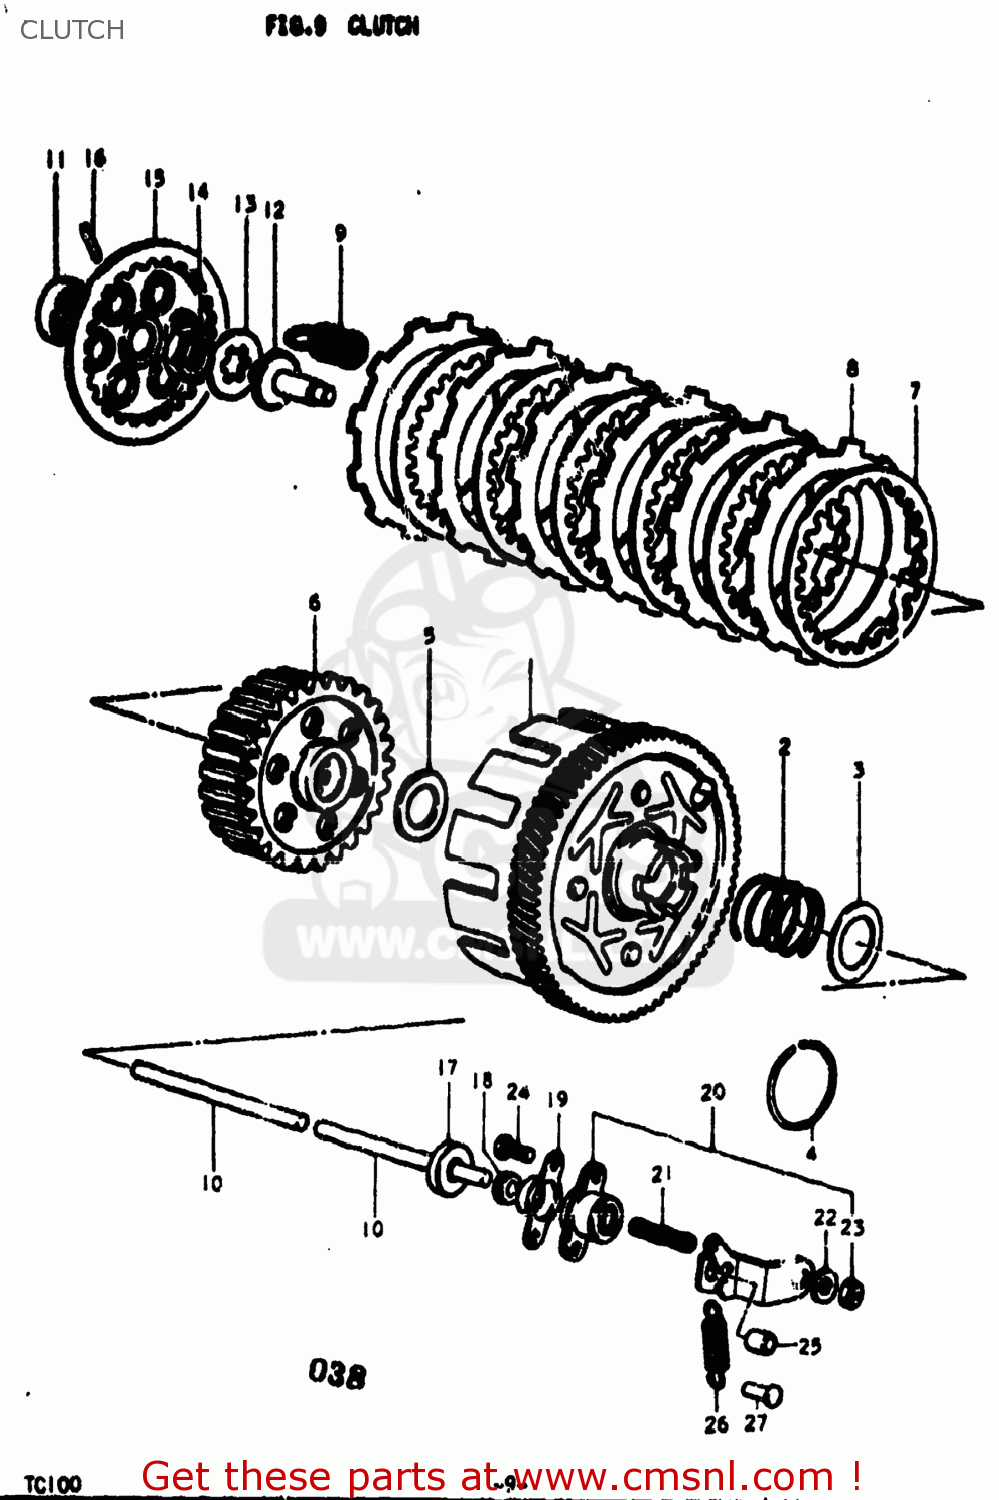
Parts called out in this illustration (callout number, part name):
1	GEAR ASSEMBLY,PRIMARY DRIVE
2	SPRING
3	SHIM, DRIVEN GEER
4	SPRING
5	WASHER
6	HUB,CLUTCH SLEEVE
7	PLATE,CLUTCH DRIVEN
8	PLATE,CLUTCH DRIVE (MCA)
9	SPRING
10	ROD,CLUTCH PUSH
11	SEAL,OIL (10X17X5)
12	ROD,CLUTCH RELEASE
13	WASHER,LOCK
14	NUT
15	PLATE,CLUTCH PRESSURE
16	PIN(2.5X19.8)
17	SEAL,OIL(5.5X16X8)
18	SEAL,DUST(5.3X13X5)
19	COVER,CLUTCH RELEASE SCREW
20	SCREW ASSEMBLY,CLUTCH RELEASE
21	SCREW
22	WASHER(6.5X16X1.2)
23	NUT
24	SCREW
25	PIECE,RELEASE ARM END
26	SPRING
27	RIVET
